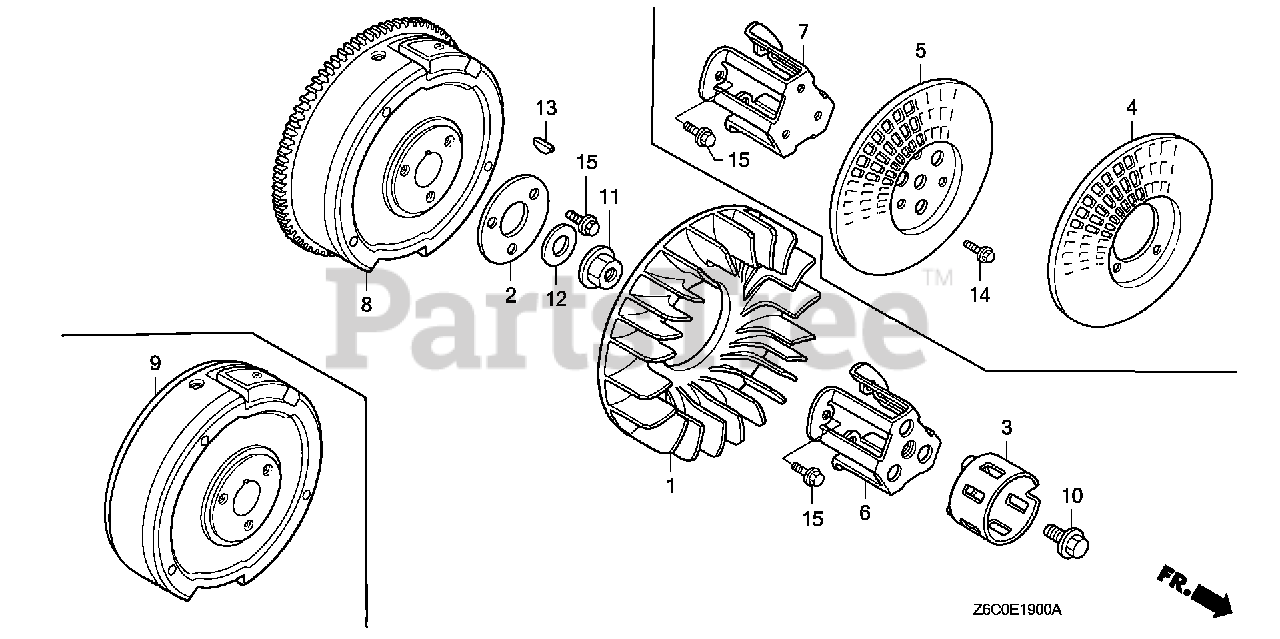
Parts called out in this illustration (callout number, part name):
1	FAN, COOLING
2	PLATE, COOLING FAN SETTING
11	NUT, FLANGE (20MM)
12	WASHER (20MM)
13	KEY, SPECIAL WOODRUFF (25X18)
15	BOLT, FLANGE (8X16)
